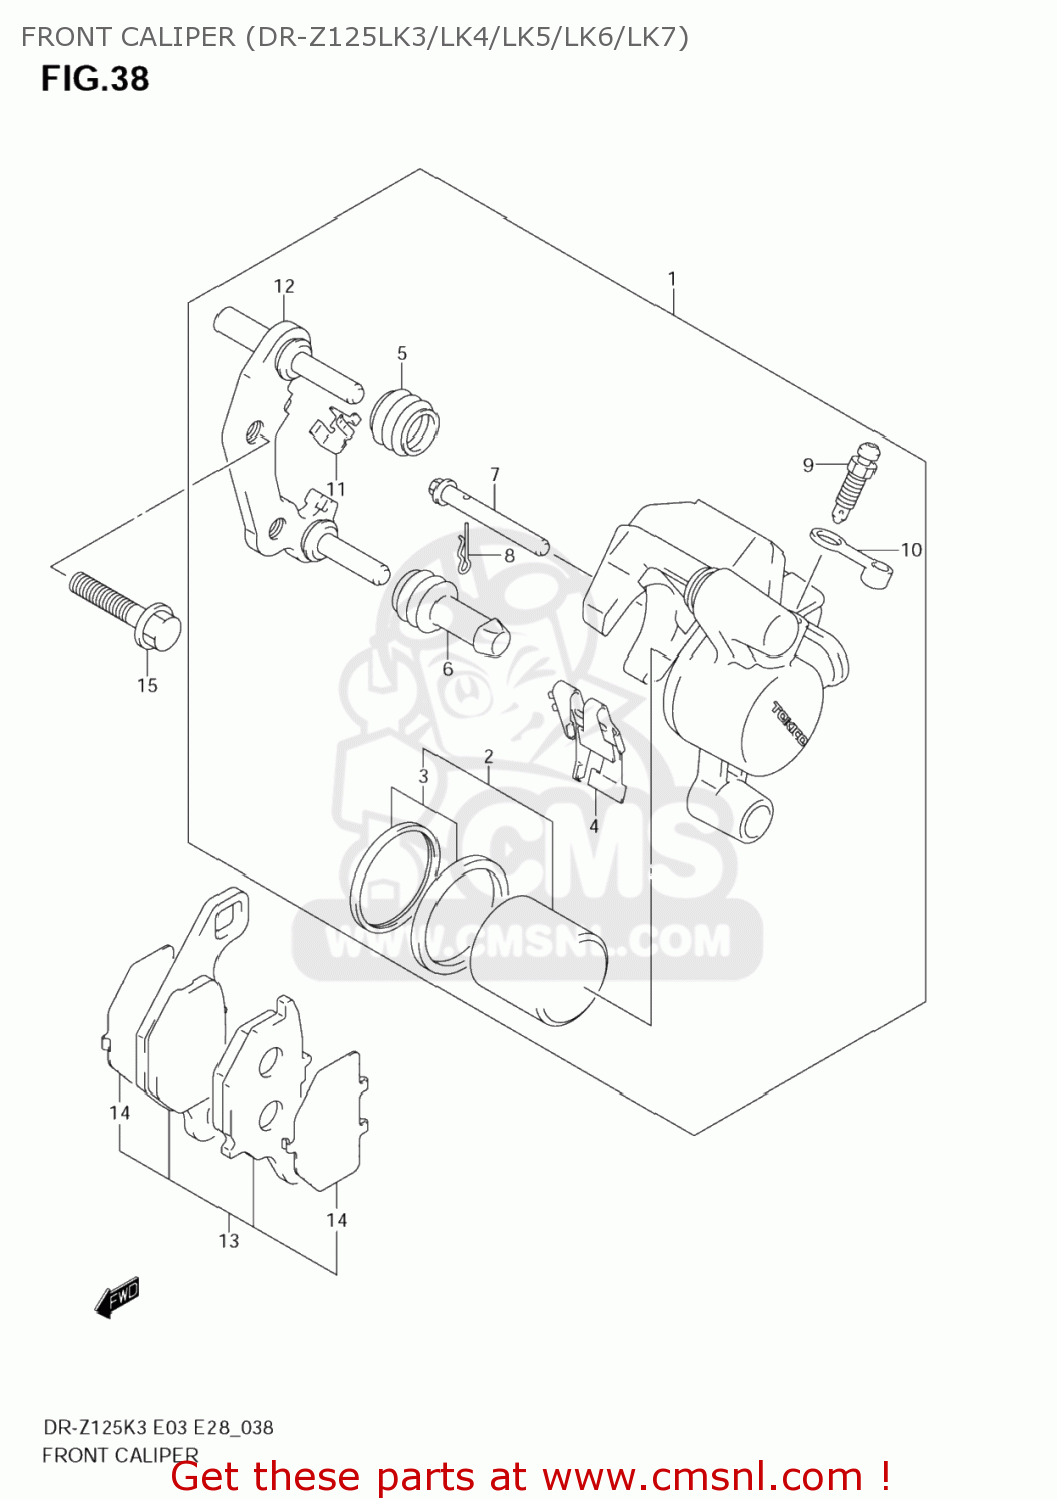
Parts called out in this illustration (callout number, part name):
1	CALIPER ASSY,FR,L
2	PISTON SET
3	SEAL SET
4	SPRING,PAD
5	BOOT,AXLE
6	INSULATOR,AXLE
7	PIN,PAD
8	CLIP,PAD PIN
9	BLEEDER
10	CAP,BLEEDER
11	GUIDE,PAD
12	CARRIER,CALIPER,L
13	PAD & SHIM SET (NAS)
14	SHIM,PAD
15	BOLT
